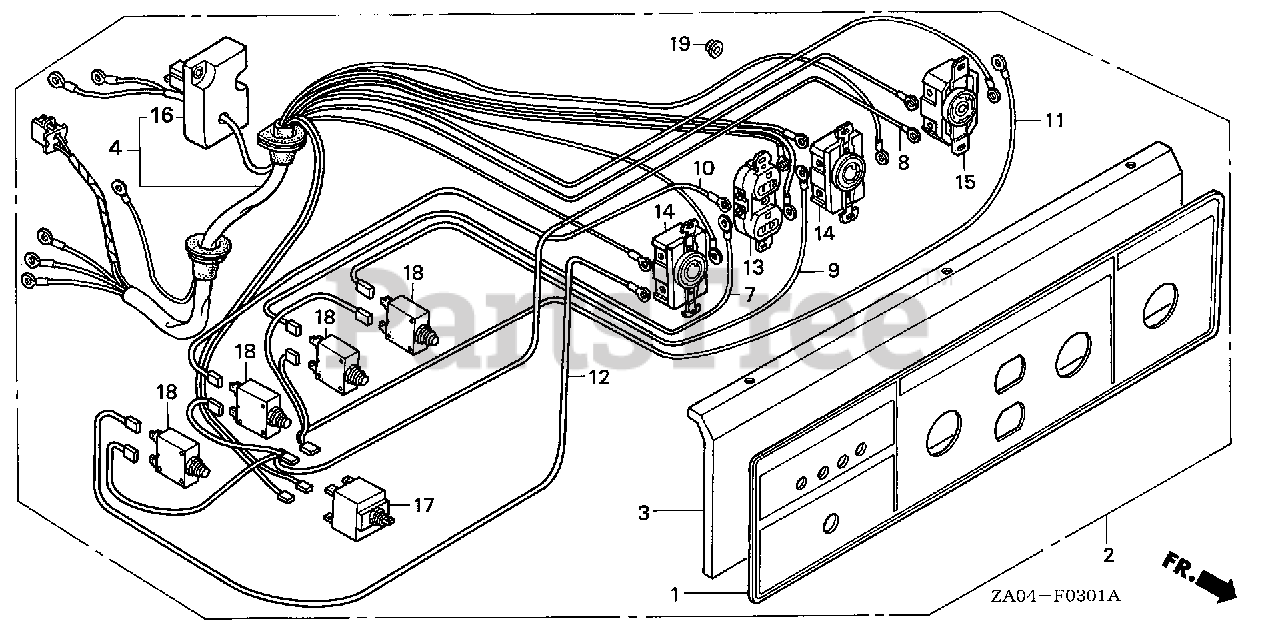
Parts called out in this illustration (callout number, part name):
1	MARK, RECEPTACLE PANEL
2	PANEL ASSY., RECEPTACLE *B9* (EX-A) (ATLANTIS BLUE)
3	PANEL, RECEPTACLE *B9* (A) (ATLANTIS BLUE)
4	HARNESS ASSY., RECEPTACLE
7	WIRE, RECEPTACLE CIRCUIT BREAKER CONNECTING
8	WIRE, RECEPTACLE CIRCUIT BREAKER CONNECTING
9	WIRE, RECEPTACLE CIRCUIT BREAKER CONNECTING
10	WIRE, RECEPTACLE CIRCUIT BREAKER CONNECTING
11	WIRE, RECEPTACLE CIRCUIT BREAKER CONNECTING
12	WIRE, RECEPTACLE CIRCUIT BREAKER CONNECTING
13	RECEPTACLE (20A/125V) (EAGLE / RONG FENG)
14	RECEPTACLE (20A/125V) (NOT AVAILABLE)
15	RECEPTACLE (30A/125-250V)
16	CONTROL UNIT, IDLE
17	PROTECTOR, CIRCUIT (21A)
18	PROTECTOR, CIRCUIT (20A)
19	NUT, FLANGE (4MM)
